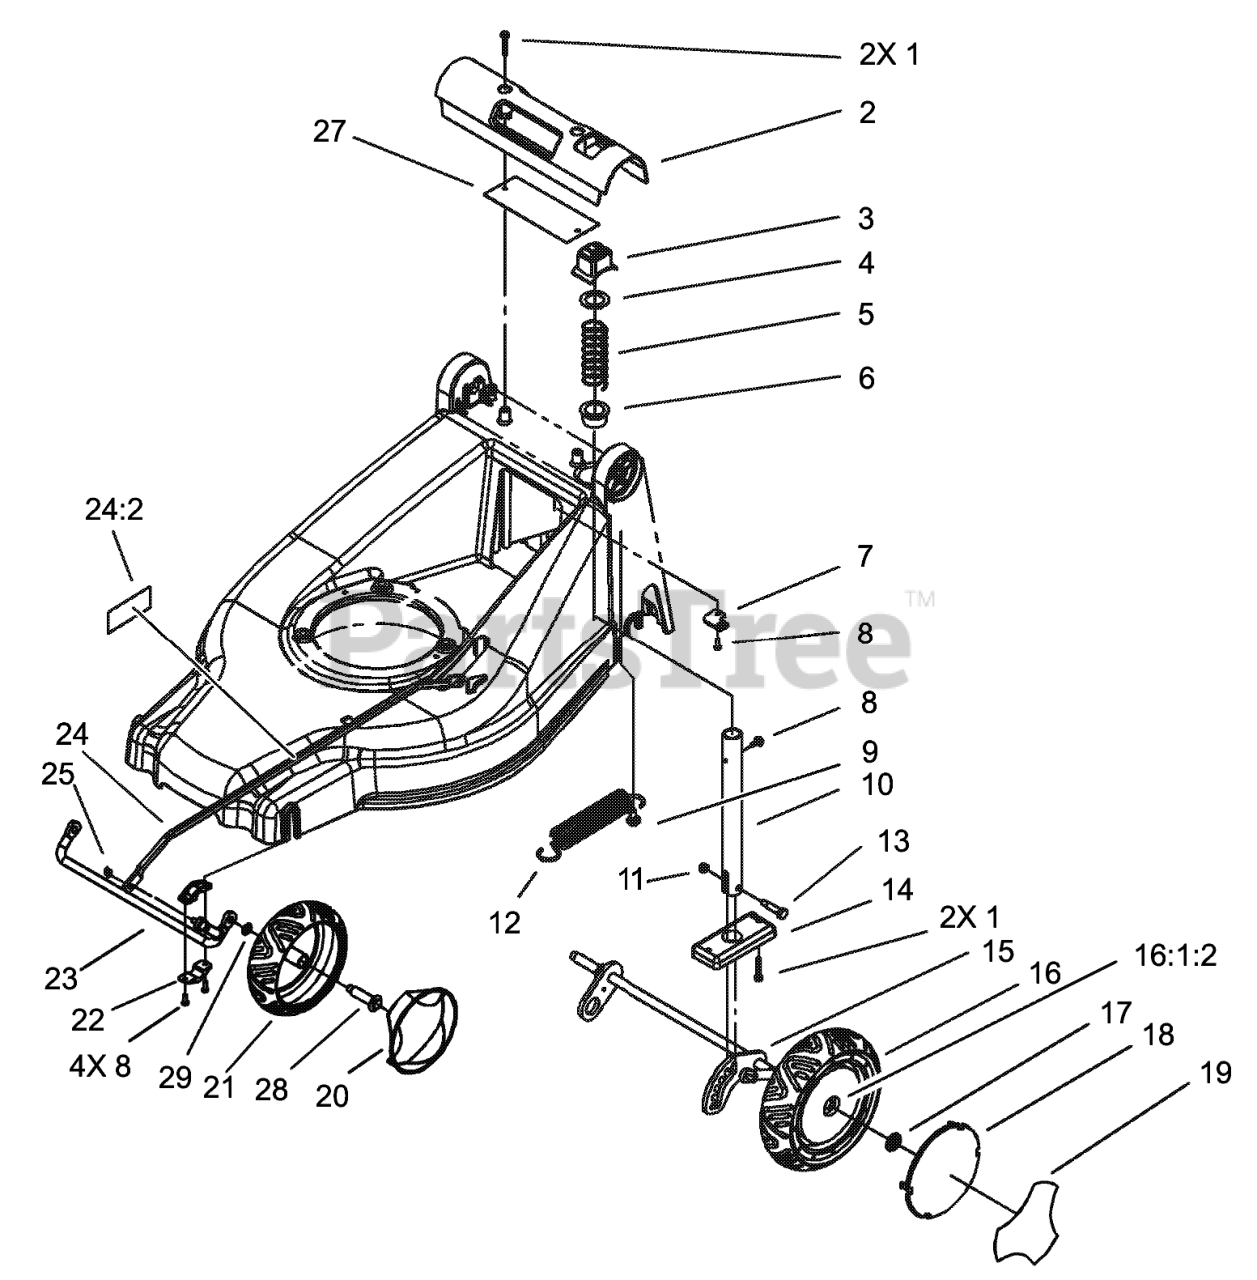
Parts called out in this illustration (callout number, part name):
1	SCREW-HWH
2	HANDLE-DECK
3	BUTTON-HOC
4	WASHER-BACKUP
5	SPRING-COMPRESSION, HOC
6	BUSHING-HOC
7	BRACKET-CABLE, TRACTION
8	SCREW-TAPTITE
9	SCREW-SHOULDER
10	PIPE-HOC
11	NUT-LOCK, NI
12	SPRING-EXTENSION, HOC
13	BOLT-SHOULDER
14	PLATE-SUPPORT, HOC
15	REAR AXLE ASM
16	WHEEL AND TIRE ASM
16:1:2	BUSHING
17	NUT-LOCK, FLANGED
18	COVER-WHEEL, SMART
19	DECAL-SMART WHEEL
20	COVER-WHEEL
21	WHEEL ASM
22	MOUNT-AXLE, FRONT
23	FRONT AXLE ASM
24	ROD ASM
24:2	DECAL-HOC
25	PALNUT
27	COVER-HANDLE
28	BOLT-SHOULDER
29	WASHER
